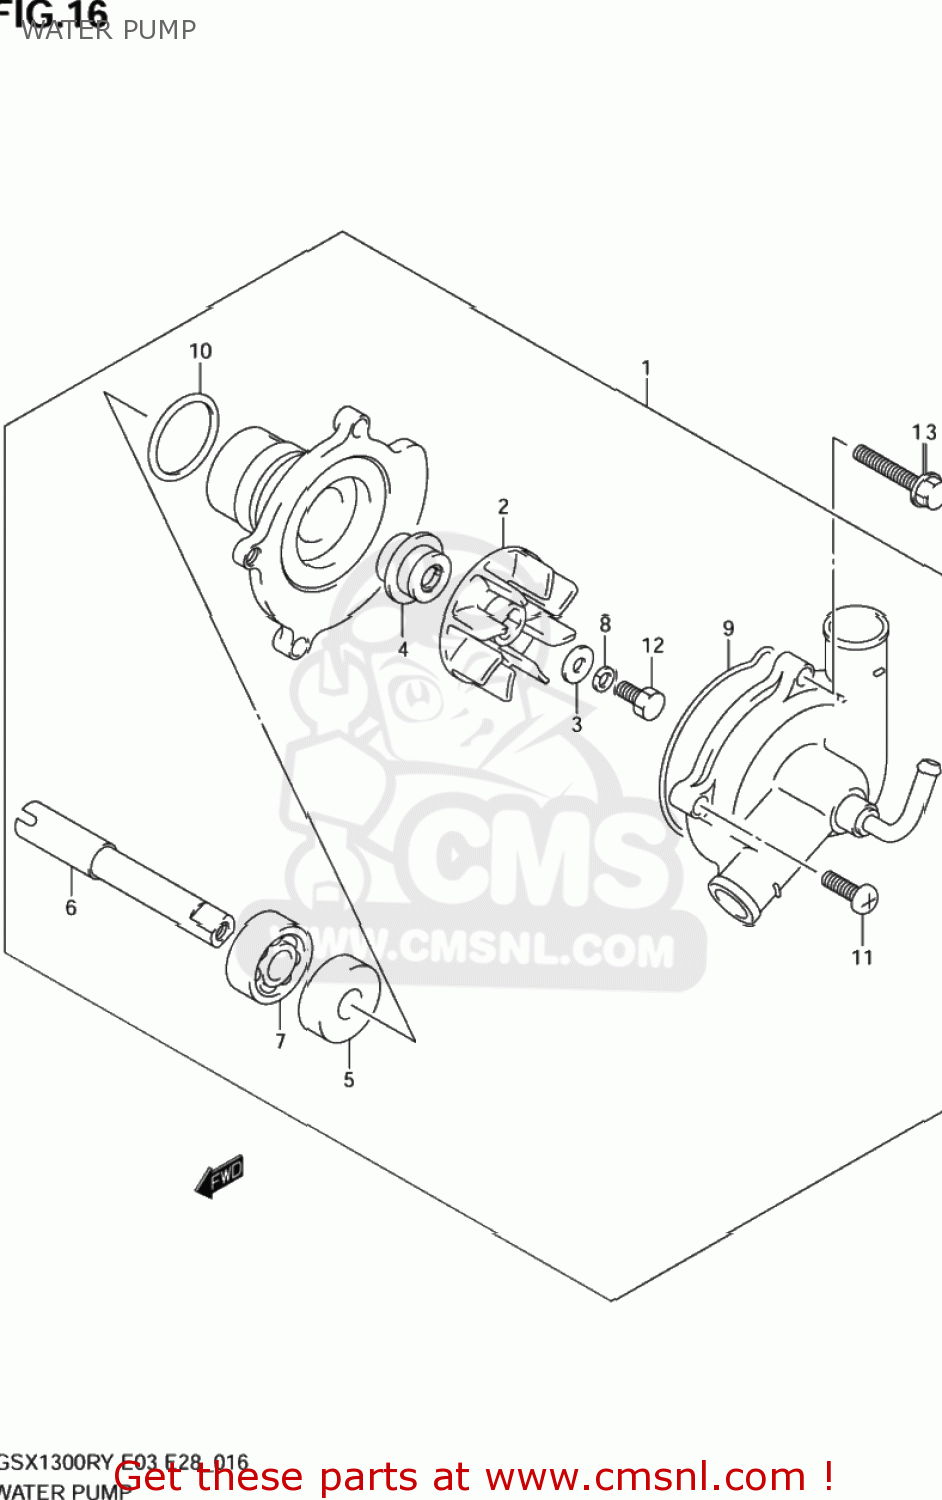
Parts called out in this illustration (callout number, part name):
1	PUMP ASSEMBLY,WATER
2	IMPELLER
3	GASKET(6X15X2.2) (NAS)
4	SEAL,MECHANICAL
5	SEAL,OIL(10X21X5)
6	SHAFT
7	BEARING(10X26X8)
8	WASHER
9	O RING
10	O RING,WATER PUMP HOLDER
11	SCREW 6X16
12	BOLT(6X13)
13	BOLT
